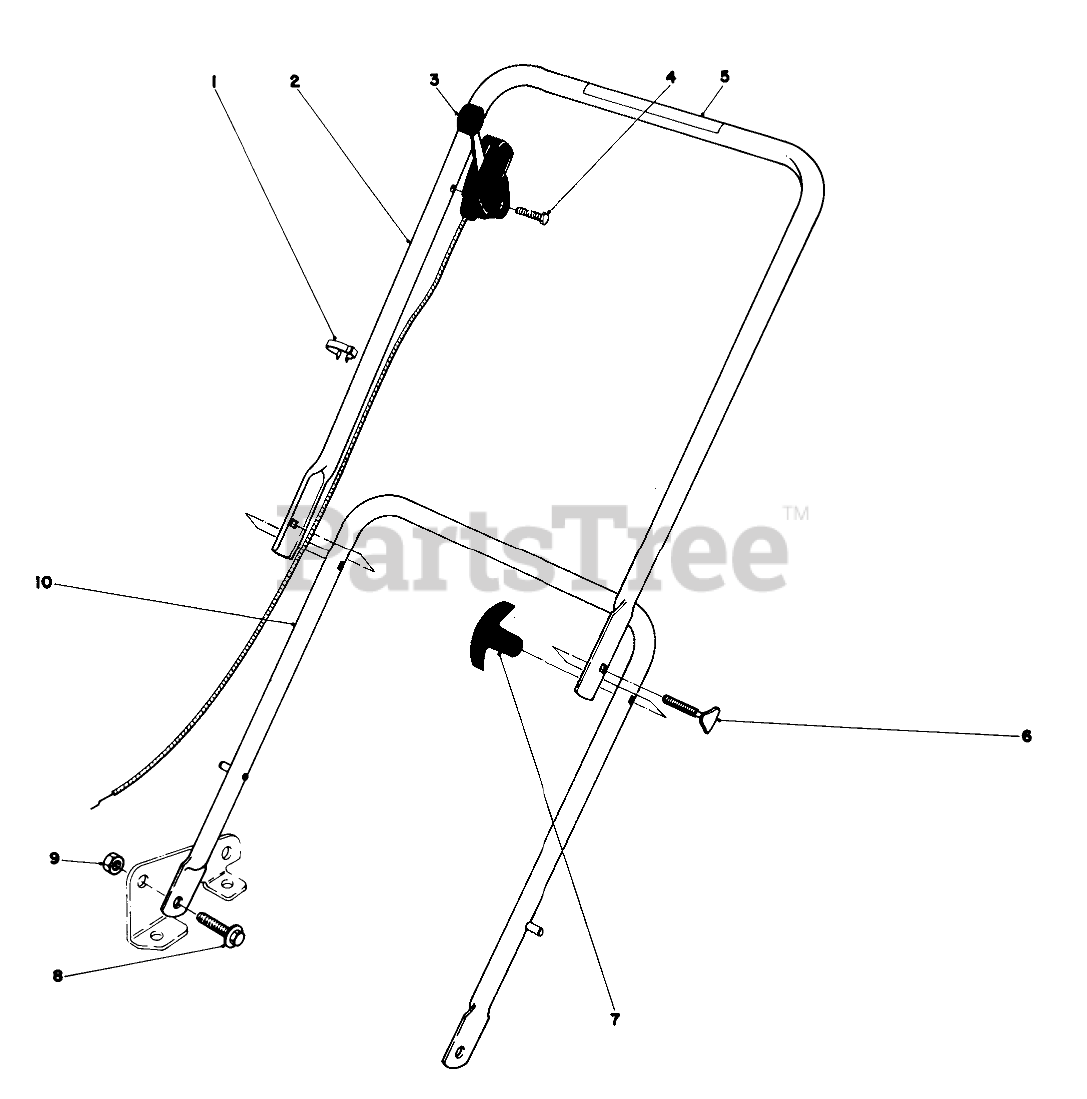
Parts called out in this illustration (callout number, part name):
1	BOWDEN CLIP
2	UPPER HANDLE
3	Throttle Control
5	Decal-Danger
6	HANDLE SCREW
8	SCREW-SHOULDER
9	NUT-LOCK, CONE
10	Lower Handle
